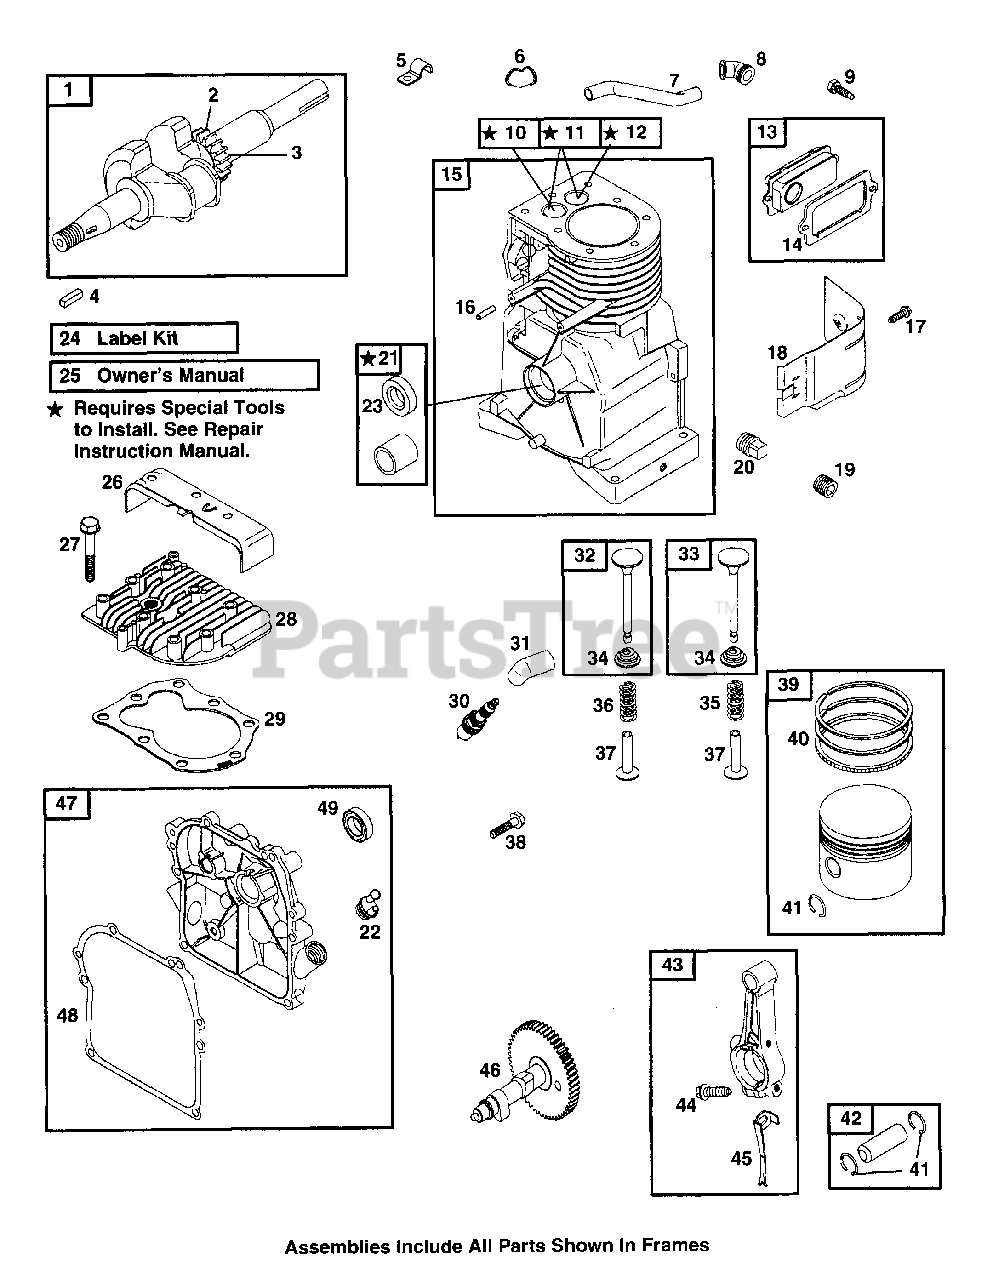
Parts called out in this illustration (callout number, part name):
1	Crankshaft
2	Timing Gear
3	Timing Key
4	Flywheel Key
5	Tube Clamp
7	Breather Tube
8	Grommet
9	Screw (Breather Assembly)
10	Valve Seat (Intake)
11	Guide Bushing (Exhaust Valve)
12	Valve Seat (Exhaust)
13	Breather Assembly
14	Breather Gasket
15	Cylinder Assembly
16	Locating Pin
17	Screw (Cylinder Shield)
18	Shield-Cylinder
19	Oil Drain Plug
20	Oil Drain Plug
21	Bushing/Seal Kit
22	Oil Fill Cap
23	Oil Seal
25	Owner's Manual
26	Cylinder Head Cover
27	Screw (Cylinder Head)
28	Cylinder Head
29	Cylinder Head Gasket
31	Sparkplug Boot
32	Exhaust Valve
33	Intake Valve
34	Valve Retainer
35	Valve Spring (Intake)
36	Valve Spring (Exhaust)
37	Valve Tappet
38	Screw (Crankcase Cover)
39	Piston Assembly (Standard)
40	Ring Set (Standard)
41	Piston Pin Lock
42	Piston Pin
43	Connecting Rod
44	Screw (Connecting Rod)
45	Connecting Rod Dipper
47	Crankcase Cover
48	Crankcase Gasket
